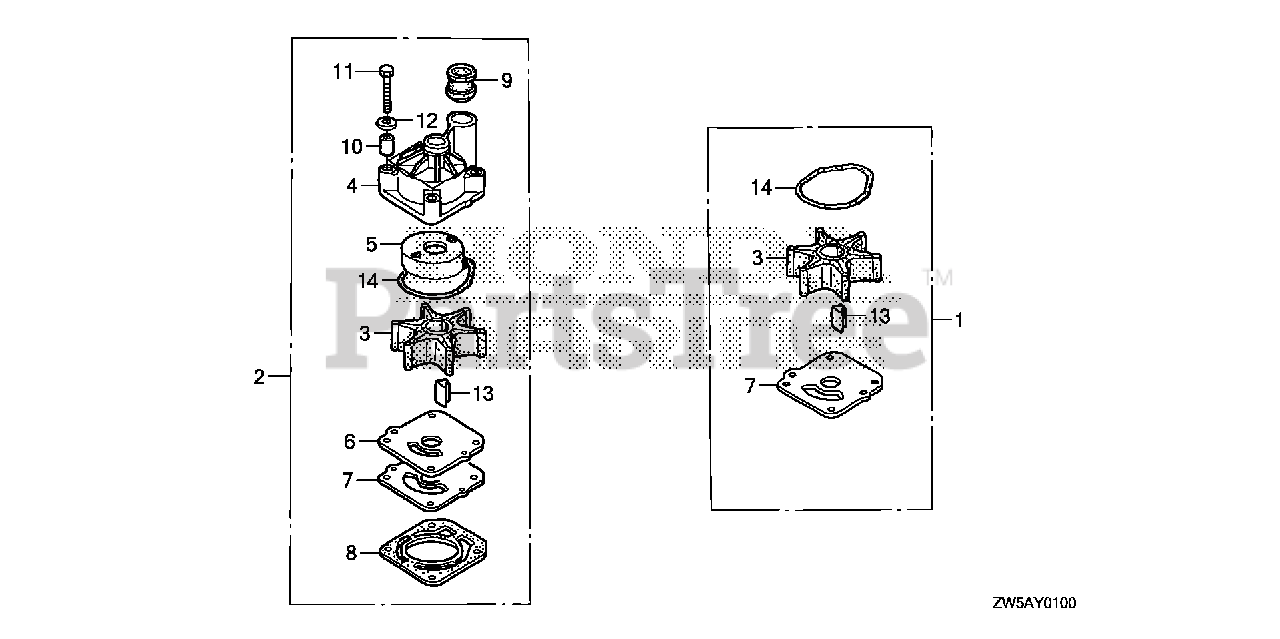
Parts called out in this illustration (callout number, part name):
1	PUMP KIT, IMPELLER
2	PUMP KIT, IMPELLER
3	IMPELLER, PUMP
4	HOUSING, IMPELLER
5	LINER, PUMP
6	COVER, IMPELLER
7	GASKET B, IMPELLER
8	GASKET, WATER PUMP
9	RING, WATER TUBE SEAL
10	COLLAR, DISTANCE
11	BOLT, HEX. (8X55)
12	WASHER (8MM)
13	KEY, WOODRUFF
14	O-RING, WATER PUMP
